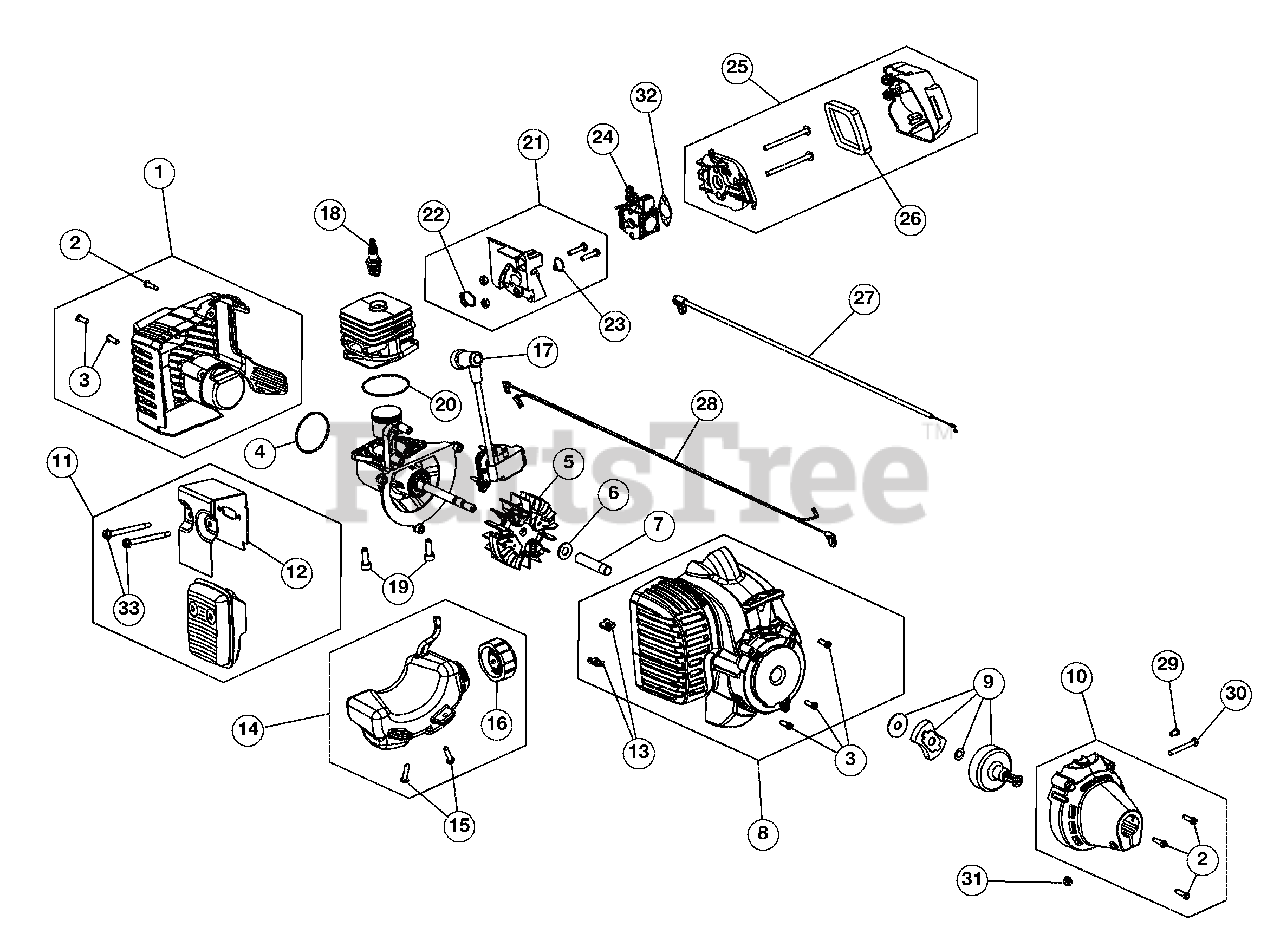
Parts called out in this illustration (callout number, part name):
1	Rear Cover Assembly (Incl. 2 & 3)
2	Cover Screw
3	Housing Screw
4	O-Ring
5	Flywheel Assembly
6	Washer
7	Spacer
8	Starter Housing (Incl. 3 & 13)
9	Starter Clutch Assembly
10	Clutch Cover (Incl. 2)
11	Muffler Assembly (Incl. 12 & 33)
12	Muffler Gasket
13	U-shaped Nut
14	Fuel Tank Assembly (Incl. 15 & 16)
15	Tank Screw
16	Fuel Cap
17	Module Assembly
18	Spark Plug
19	Crankcase Bolt
20	Crankcase O-Ring
21	Insulator Assembly (Incl. 22 & 23)
22	Insulator O-Ring
23	Carburetor O-Ring
24	Carburetor
25	Aircleaner Cover Assembly (Incl. 26)
26	Aircleaner Filter
27	Throttle Cable
28	Lead Wires
29	Anti-rotation Screw
30	Clamp Screw
31	Clamp Nut
32	Air Cleaner Gasket
33	Muffle Screws
